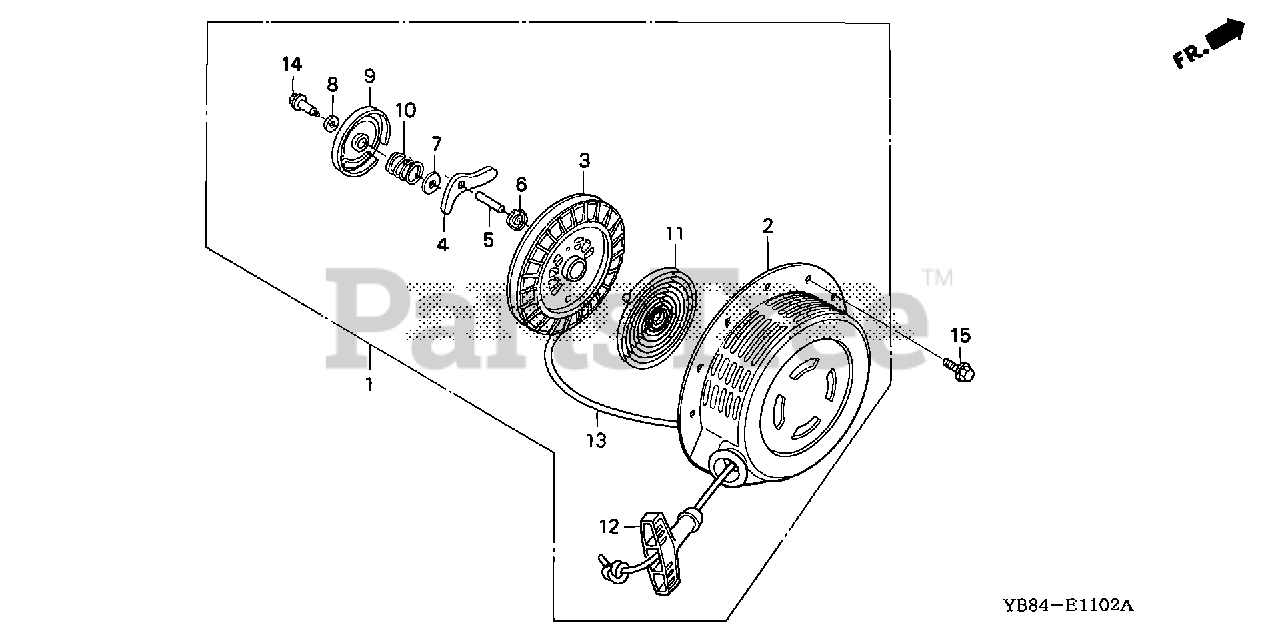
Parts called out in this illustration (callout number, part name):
1	STARTER ASSY., RECOIL *R8* (BRIGHT RED)
2	CASE, RECOIL STARTER *R8* (BRIGHT RED) (NOT AVAILABLE)
3	REEL, STARTER (NOT AVAILABLE)
4	RATCHET, STARTER
5	SHAFT, RATCHET
6	PLATE, GUIDE
7	PLATE A, FRICTION (NOT AVAILABLE)
8	PLATE B, FRICTION
9	COVER, STARTER REEL (NOT AVAILABLE)
10	SPRING, FRICTION (D=18.5MM / L=20.5MM)
10	SPRING, FRICTION
11	SPRING, RETURN
12	GRIP, STARTER
13	ROPE, RECOIL STARTER
14	BOLT, REEL COVER (NOT AVAILABLE)
15	BOLT, FLANGE (6X8)
